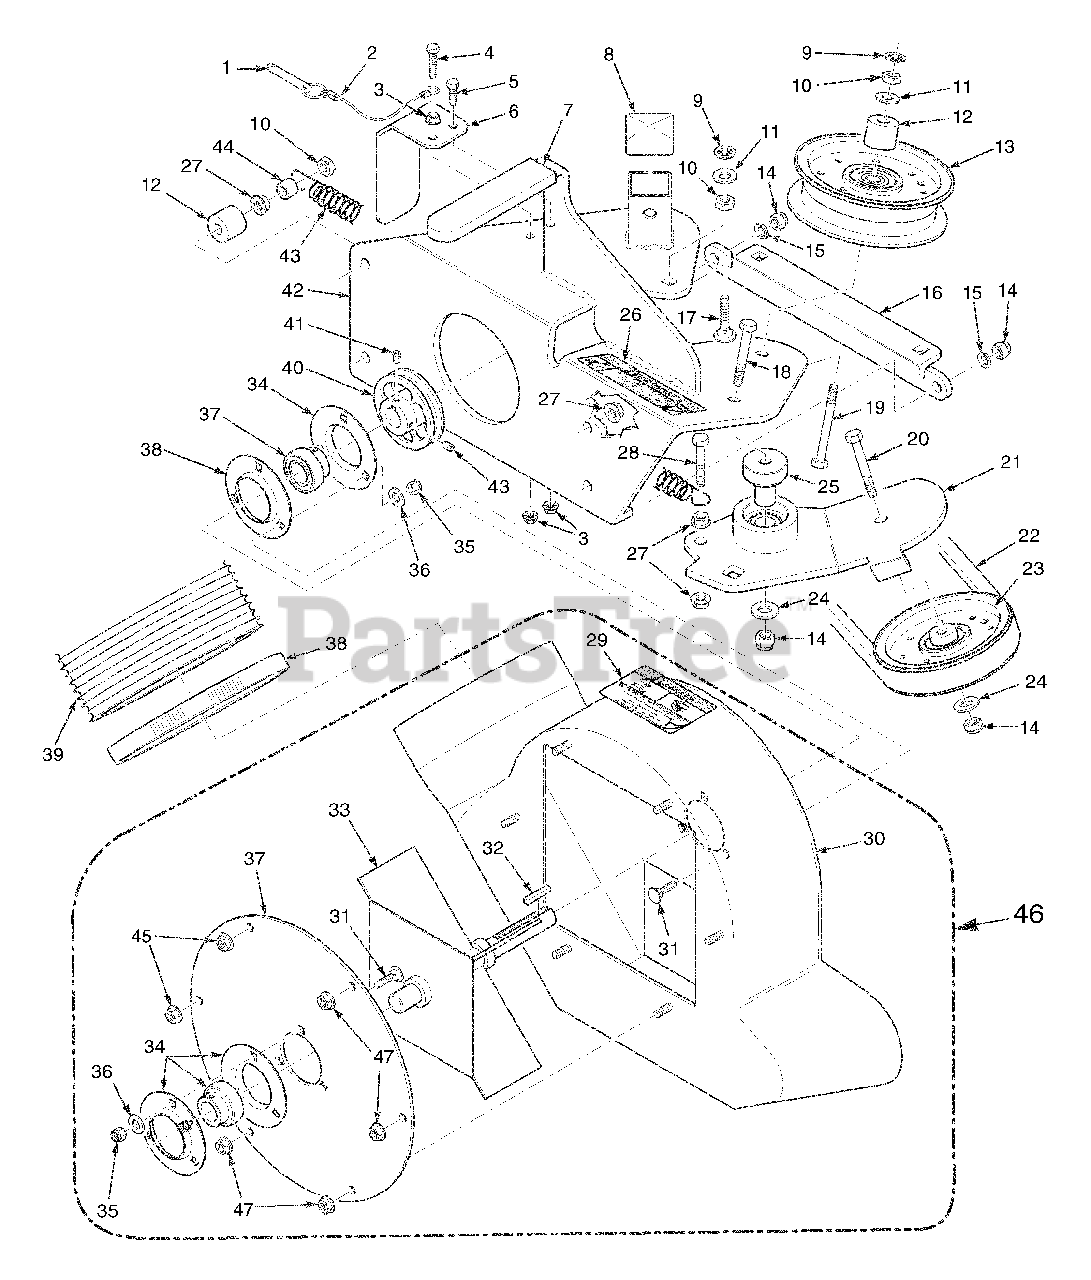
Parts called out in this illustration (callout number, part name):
1	Pin, Ring 2-1/4" Long
2	Lanyard, Deck Height Pin
3	Nut, Serr. Flange 1/4-20
4	Bolt, Hex Head 1/4-20 x 1-1/4"
5	Bolt, Hex Head 1/4-20 x 3/4"
6	Belt Cover, Rear
7	Grip, Blower Lever
8	Cap, Square
9	Nut, Push On 3/8 Thread
10	Lock Nut, 3/8-16
11	Flatwasher, 3/8-.391 x .938 x .105
12	Spacer
13	Pulley, Idler 4" Dia.
14	Nut, Elastic Stop 3/8-16
15	Lockwasher, 3/8-16
16	Plate, Catch Mounting
17	Bolt, Carr. 3/8-16 x 1-1/2"
18	Bolt, Hex Head 3/8-16 x 2-1/4"
19	Bolt, Hex Head 3/8-16 x 3-1/4"
20	Bolt, Hex Head 3/8-16 x 2"
21	Idler Arm Weldment
22	Belt, GC-STC
23	Pulley, 3" O.D.
24	Washer, 3/8 Hardened
25	Pivot, Idler
26	Decal, Belt Cover
27	Nut, Serr. Flange 3/8-16
28	Bolt, Hex Head 3/8-16 x 1-1/2 Gr. 8
29	Decal, Danger
30	Blower Housing Weldment,
31	Bolt, Carr. 5/16-18 x 3/4" Gr. 5
32	Key, 1/4 x 1/4 x 1-1/2"
33	Fan Weldment
34	Bearing with Locking Collar
35	Nut, Elastic Stop 5/16-18
36	Flatwasher, 5/16-.344 x .688 x .065
37	Cover, Blower Housing
38	Clamp, 6-1/2" Max Dia.
39	Hose, 6" Dia.
40	Pulley, 4-3/4" O.D. - 1" Bore
41	Set Screw, 5/16-18 x 3/8"
42	Frame Weldment, Blower Mount
43	Spring, Main Drive
44	Spacer
45	Nut, Serr. Flange 5/16-18
46	Blower Housing Assembly
